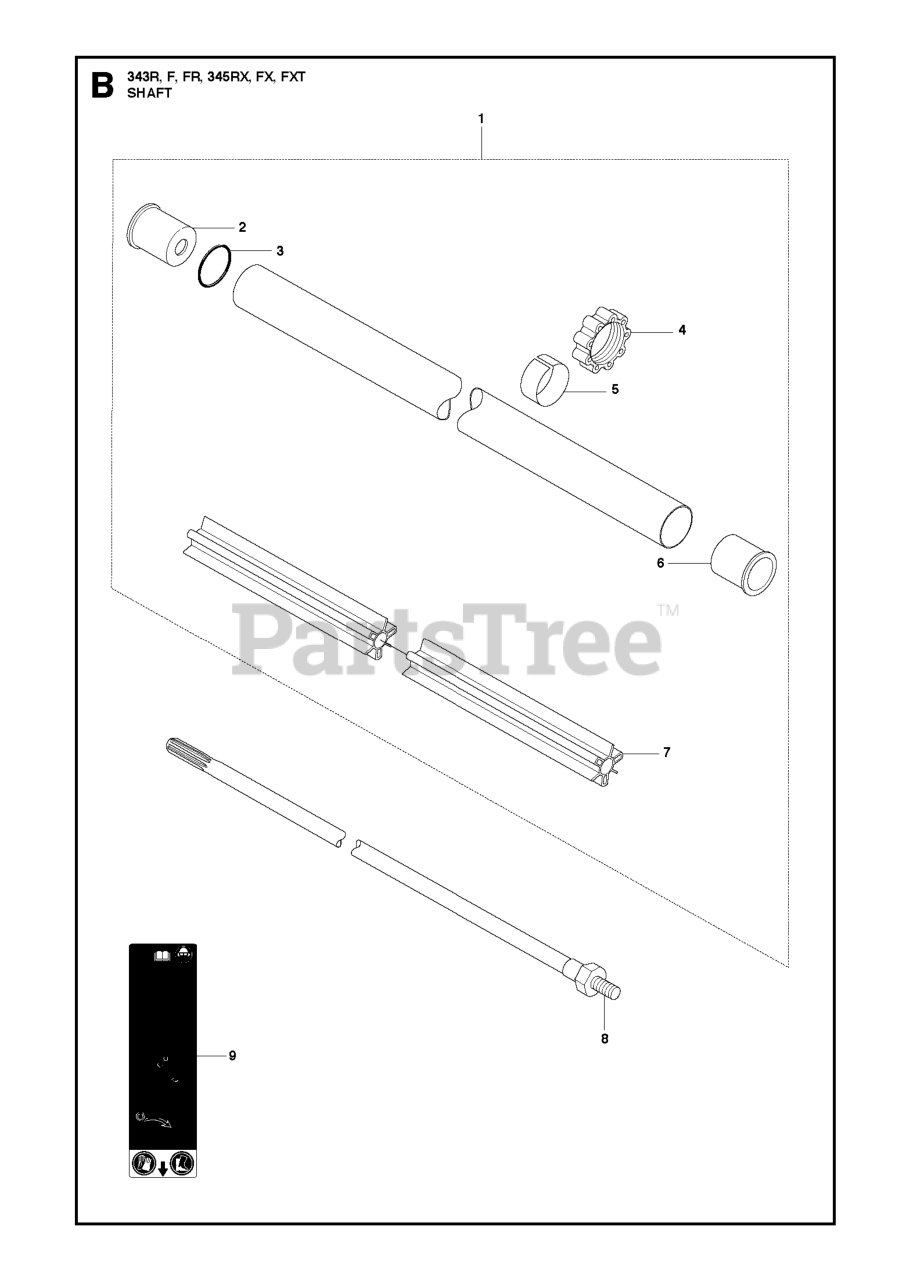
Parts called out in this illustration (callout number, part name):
1	RP DRIVE SHAFT TUBE
1	TUBE
2	SPACER SLEEVE
4	MOVEMENT LIMITER
5	%BAND
6	SPACER SLEEVE
7	GUIDE
8	SHAFT
8	DRIVE SHAFT
9	WARNING DECAL
